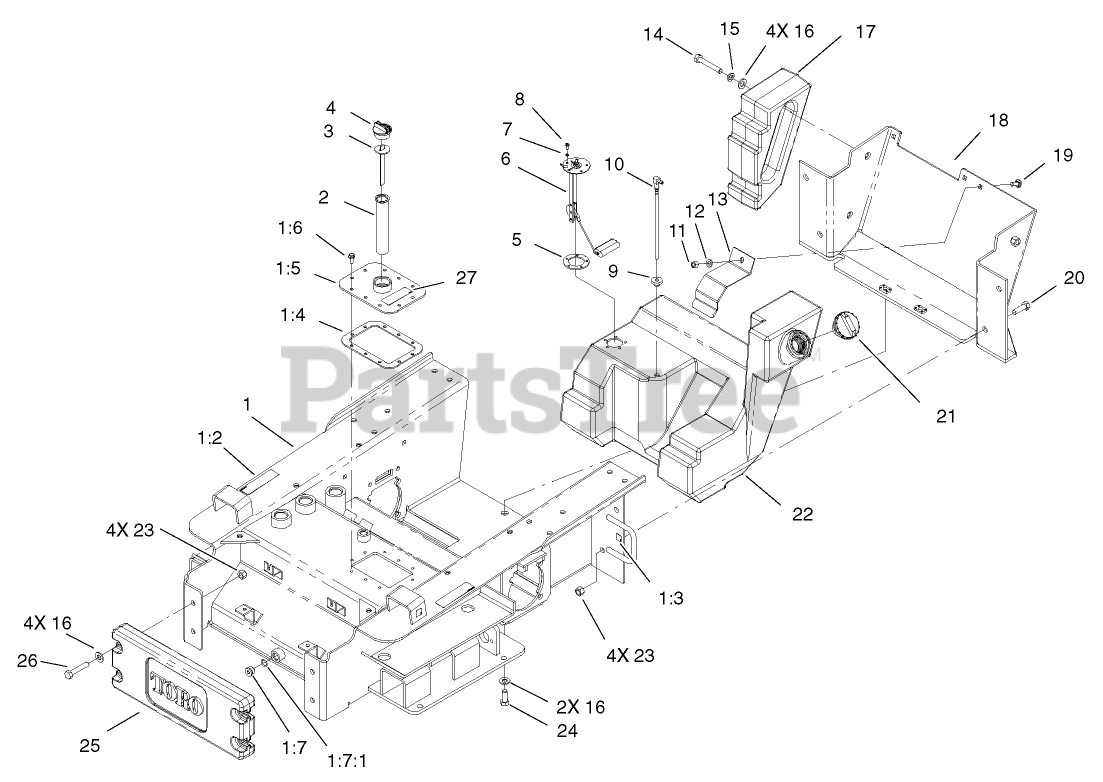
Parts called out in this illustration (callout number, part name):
1	CHASSIS ASM
1:2	DECAL-PINCH
1:3	DECAL-POINT, LIFT
1:4	GASKET-COVER, ACCESS
1:5	TANK COVER ASM
1:6	SCREW
1:7	PLUG-HEX
1:7:1	O-RING
2	FILTER-SCREEN
3	DIPSTICK-OIL
4	PLUG-PLASTIC
5	GASKET-SENDER, FUEL
6	SENDER-FUEL
7	WASHER-LOCK
8	SCREW-PPH
9	BUSHING
10	PIPE-STAND
11	NUT-LOCK, NI
12	WASHER-FLAT
13	CLAMP-TANK, FUEL
14	SCREW-HH
15	WASHER-LOCK
16	WASHER-FLAT
17	COUNTERWEIGHT-REAR
18	REAR FRAME COVER ASM
19	SCREW-CARR
20	SCREW-HH
21	CAP-FUEL
22	TANK-FUEL
23	NUT-LOCK, NI
24	SCREW-HH
25	COUNTERWEIGHT-FRONT
26	SCREW-HH
27	DECAL-OIL, HYD
